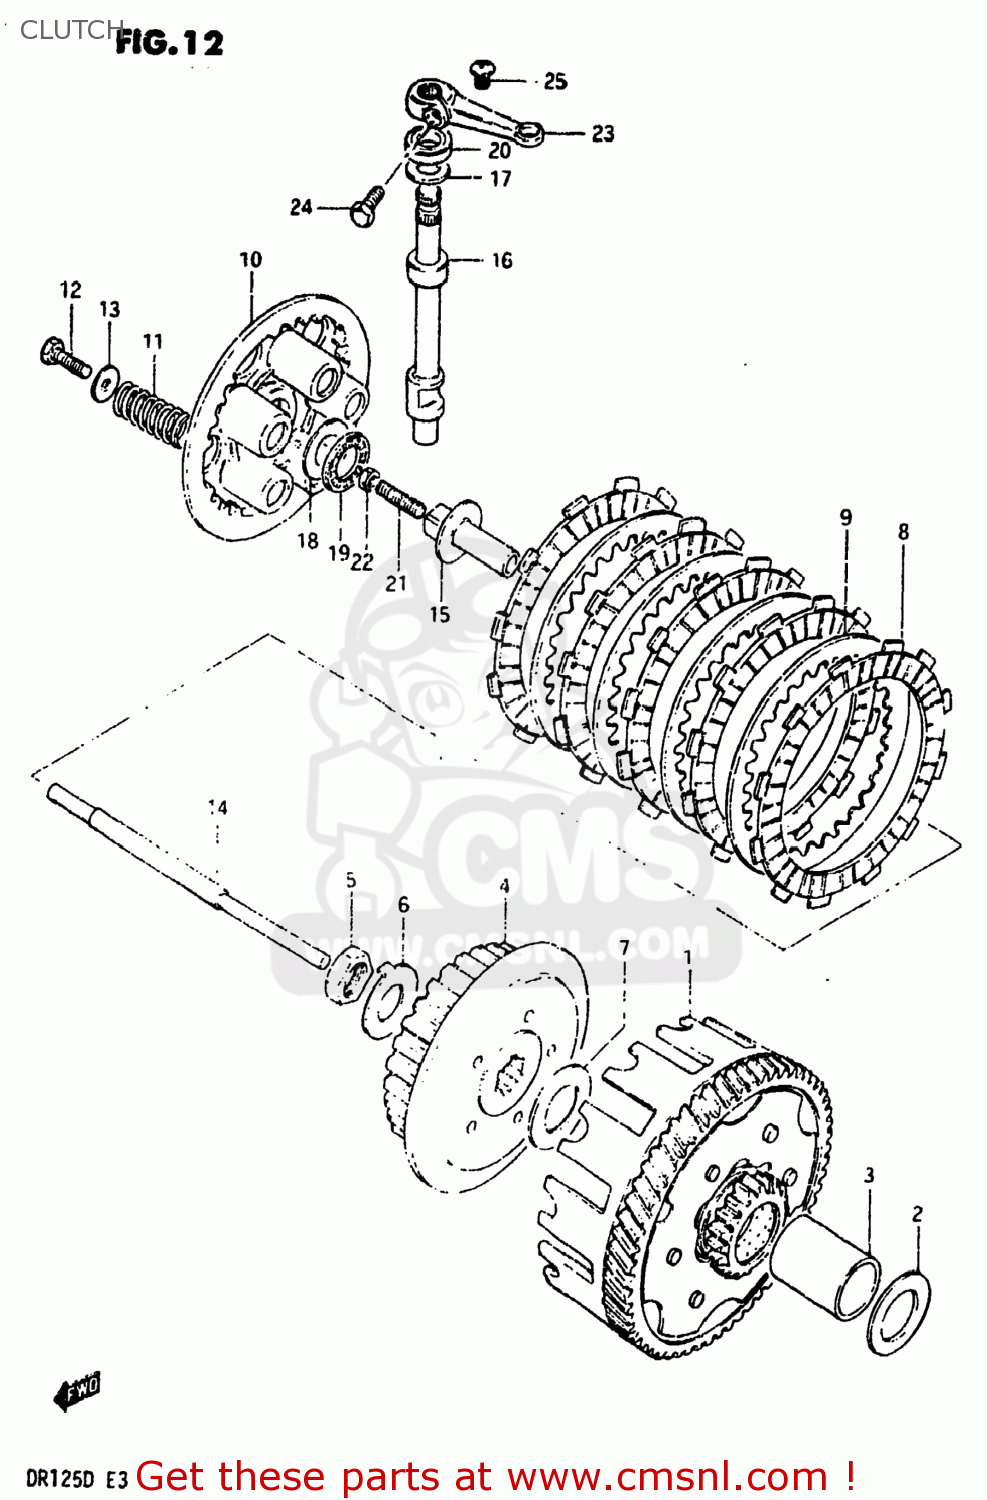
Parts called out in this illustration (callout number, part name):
1	GEAR ASSEMBLY,PRIMARY DRIVE
2	WASHER
3	WASHER (20X34X1)
4	HUB,CLUTCH SLEEVE
5	NUT
6	WASHER
7	WASHER
8	PLATE,CLUTCH DRIVE
9	PLATE,CLUTCH DRIVEN (NAS)
10	PLATE,CLUTCH PRESSURE
11	SPRING
12	BOLT(5X16)
13	WASHER (5.5X16X1.2)
14	ROD,CLUTCH PUSH
15	PIECE,CLUTCH PUSH
16	CAMSHAFT,CLUTCH RELEASE
17	WASHER,THRUST
18	WASHER
19	BEARING(15X28X2)
20	OIL SEAL
21	SCREW
22	NUT 6MM
23	ARM,CLUTCH RELEASE
24	BOLT, UPPER
25	SCREW
